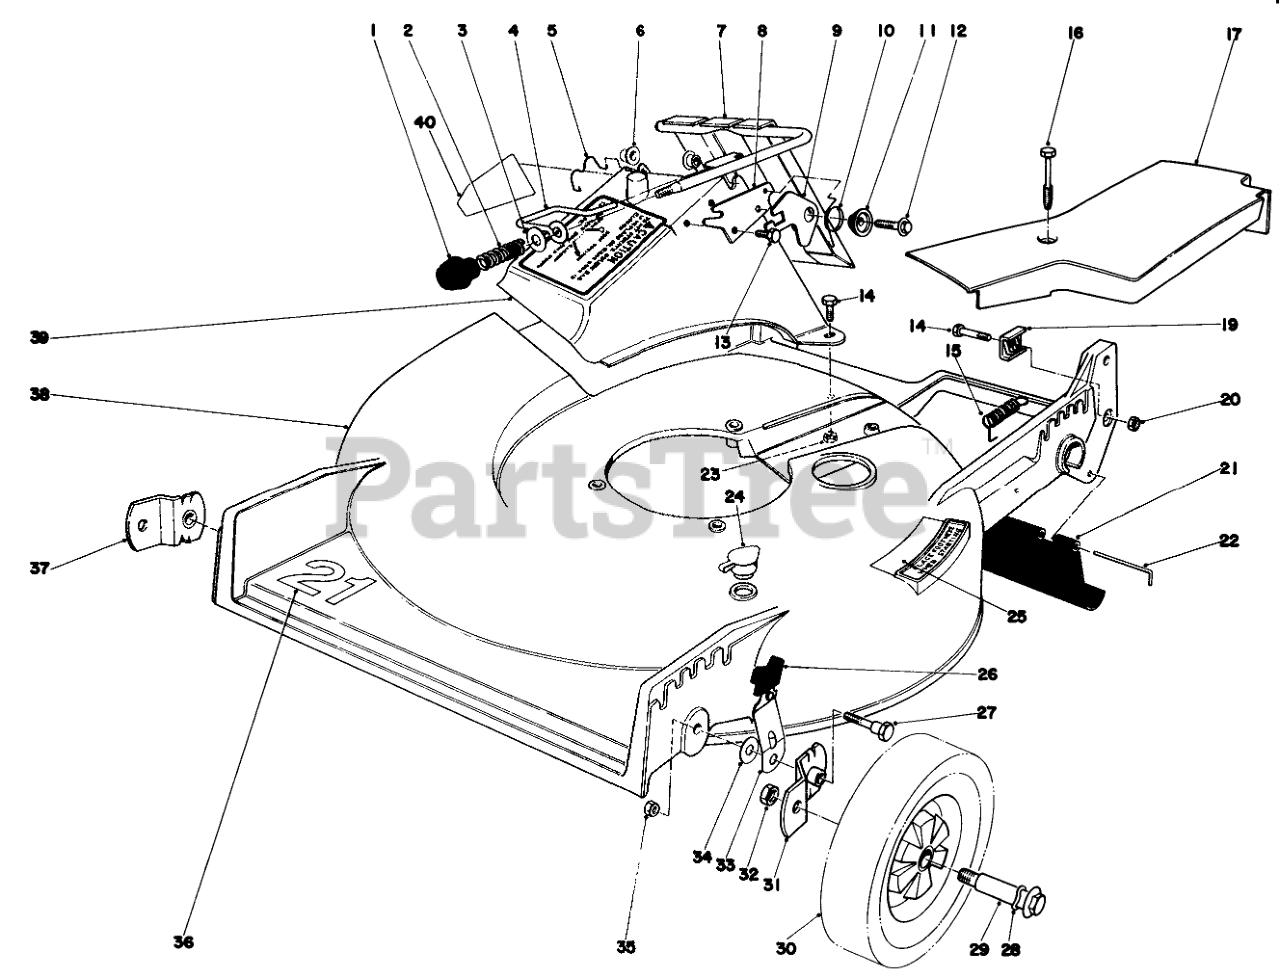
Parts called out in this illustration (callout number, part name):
2	COMPRESSION SPRING
3	WASHER
4	DOOR LATCH
5	DOOR RETAINER
6	BUSHING-NYLON
7	DOOR & HANDLE WA
8	DOOR LATCH PLATE
9	SAFETY LATCH
10	TORSION SPRING
11	Latch Spacer
12	Screw
13	SCREW-HWH
14	SCREW-HH
15	IDLER SPRING
16	SCREW-HHFTF
17	Belt Cover
19	CLAMP-CABLE
20	NUT-JAM
21	SHIELD - TRAILING
22	Rod Shield
23	NUT-LOCK, NI
24	WASHOUT PLUG
25	Decal-Place Foot Here
26	KNOB-ARM
27	PIVOT SCREW
28	SPRING WASHER
29	BOLT-WHEEL
30	WHEEL TIRE ASM 8 IN
31	PIVOT ARM ASM A
32	Nut
33	SPRING ARM ASM (R&S)
34	WASHER-PIVOT
35	Nut
36	Decal 21"
37	PIVOT ARM ASM B
38	Housing
39	DISCHARGE CHUTE B
40	Decal-Attention
